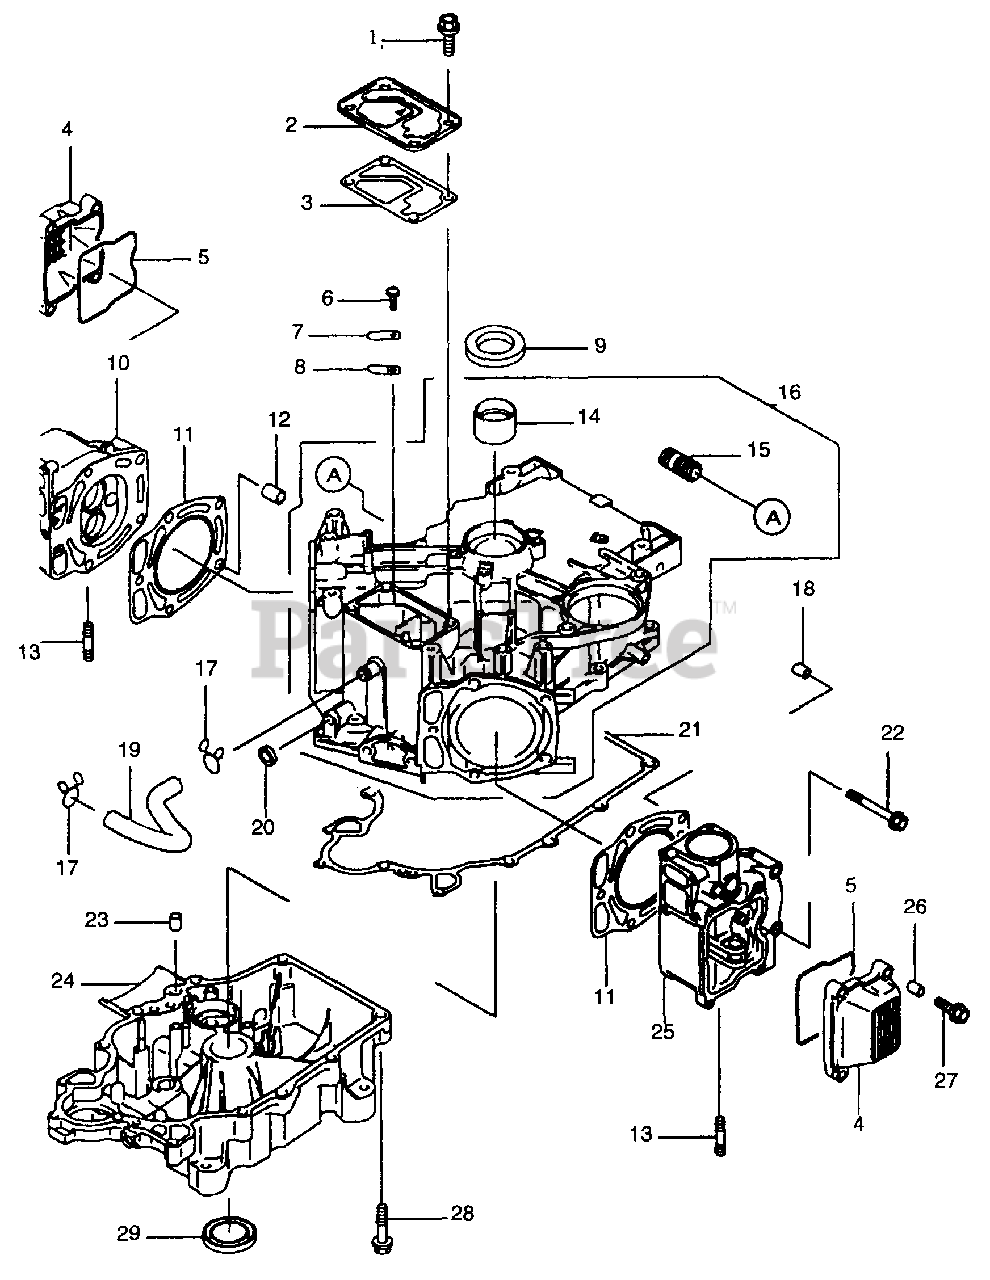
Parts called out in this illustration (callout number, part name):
1	Flanged Bolt
5	Gasket-Rocker Case
9	Oil Seal
10	Head-Comp-Cylinder
14	Plane Bearing
16	Crankcase-Comp
21	Gasket Crankcase Cover
22	Flanged Bolt
24	Cover Crankcase
25	Head Comp Cylinder
27	Flanged Bolt
28	Flanged Bolt
